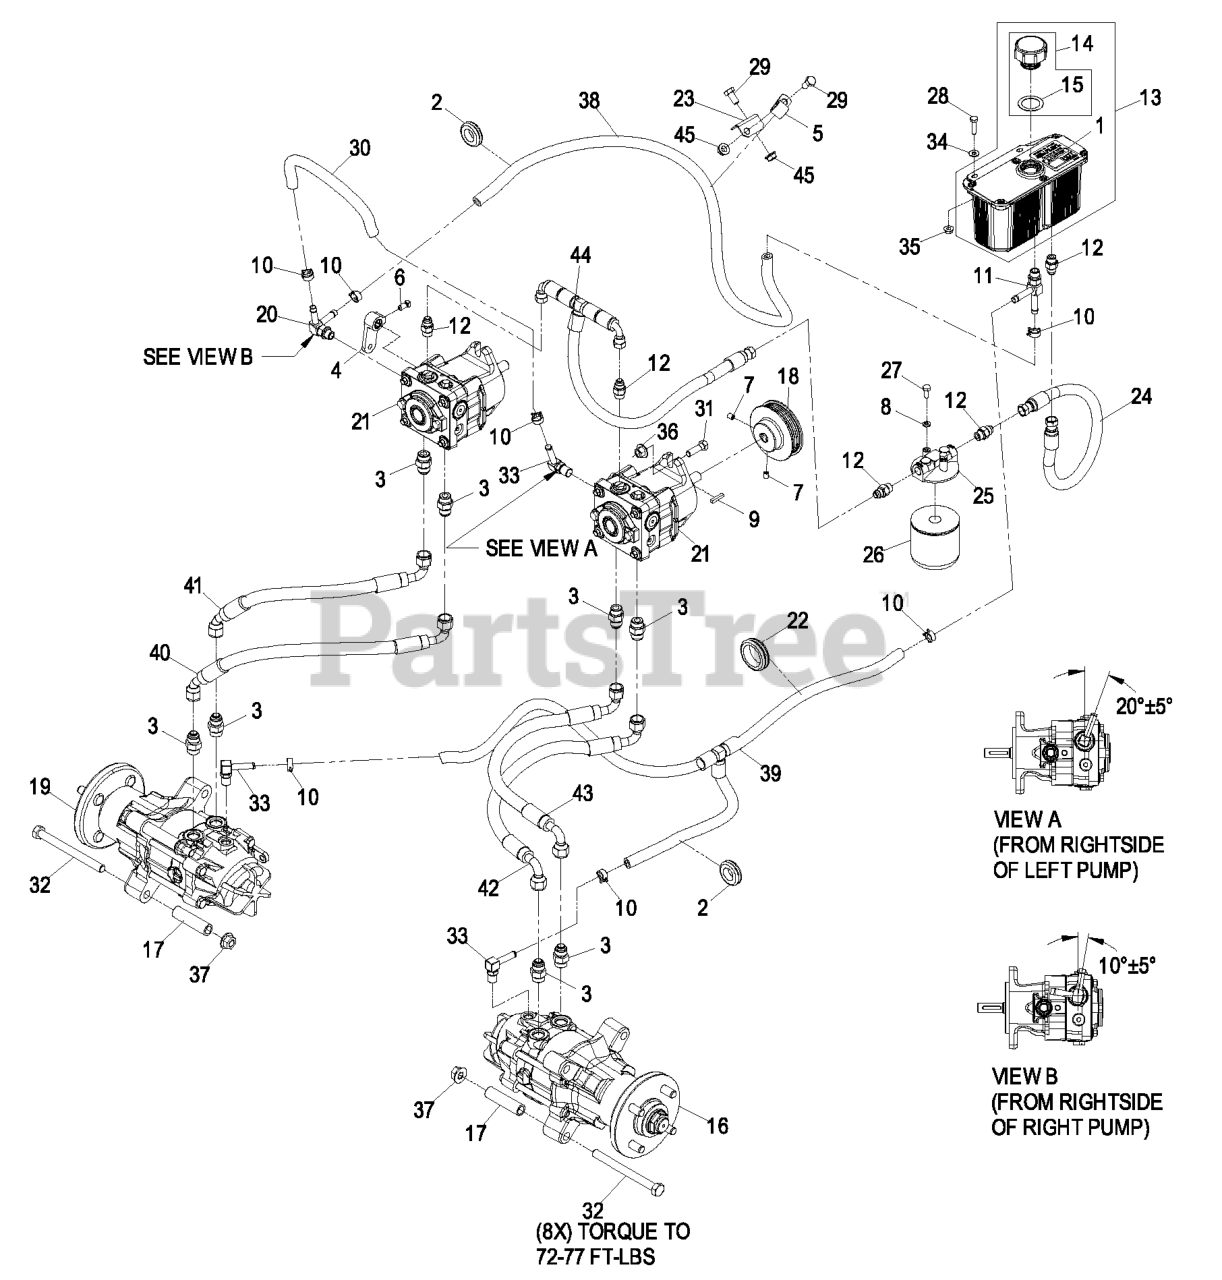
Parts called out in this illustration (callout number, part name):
1	DECAL-HYDRAULIC TANK
2	GROMMET
3	FITTING-STRAIGHT
4	ARM-CONTROL, PUMP
5	CLIP-LOOM
6	SCREW-SET
7	SCREW-SET
8	WASHER-LOCK
10	CLAMP-HOSE
11	ADAPTER-RUN, TEE
12	FITTING-STRAIGHT
13	HYD RESERVOIR ASM
14	KIT,HYD RES CAP W/GASKET
15	GASKET-CAP
16	MOTOR,PRM18-LH
19	MOTOR,PRM18-RH
20	ADAPTER-TEE
22	GROMMET
23	BRACKET-CLAMP
24	HYDRAULIC HOSE ASM
25	HEAD-FILTER
26	FILTER-25 MICRON, BI-DIRE
27	SCREW-HH
28	SCREW-HH
29	SCREW-HH
30	HOSE-HYD
31	SCREW-HH
32	SCREW-HH
33	FITTING-ELBOW, 90
34	WASHER-FLAT
36	NUT-FLANGE
37	NUT-HHF
38	HOSE-HYD
39	ASM,HYDRAULIC HOSE
40	ASM,HYDRAULIC HOSE
41	ASM,HYDRAULIC HOSE
42	ASM,HYDRAULIC HOSE
43	ASM,HYDRAULIC HOSE
44	HYDRAULIC HOSE ASM
45	NUT-HHF, WHIZ
